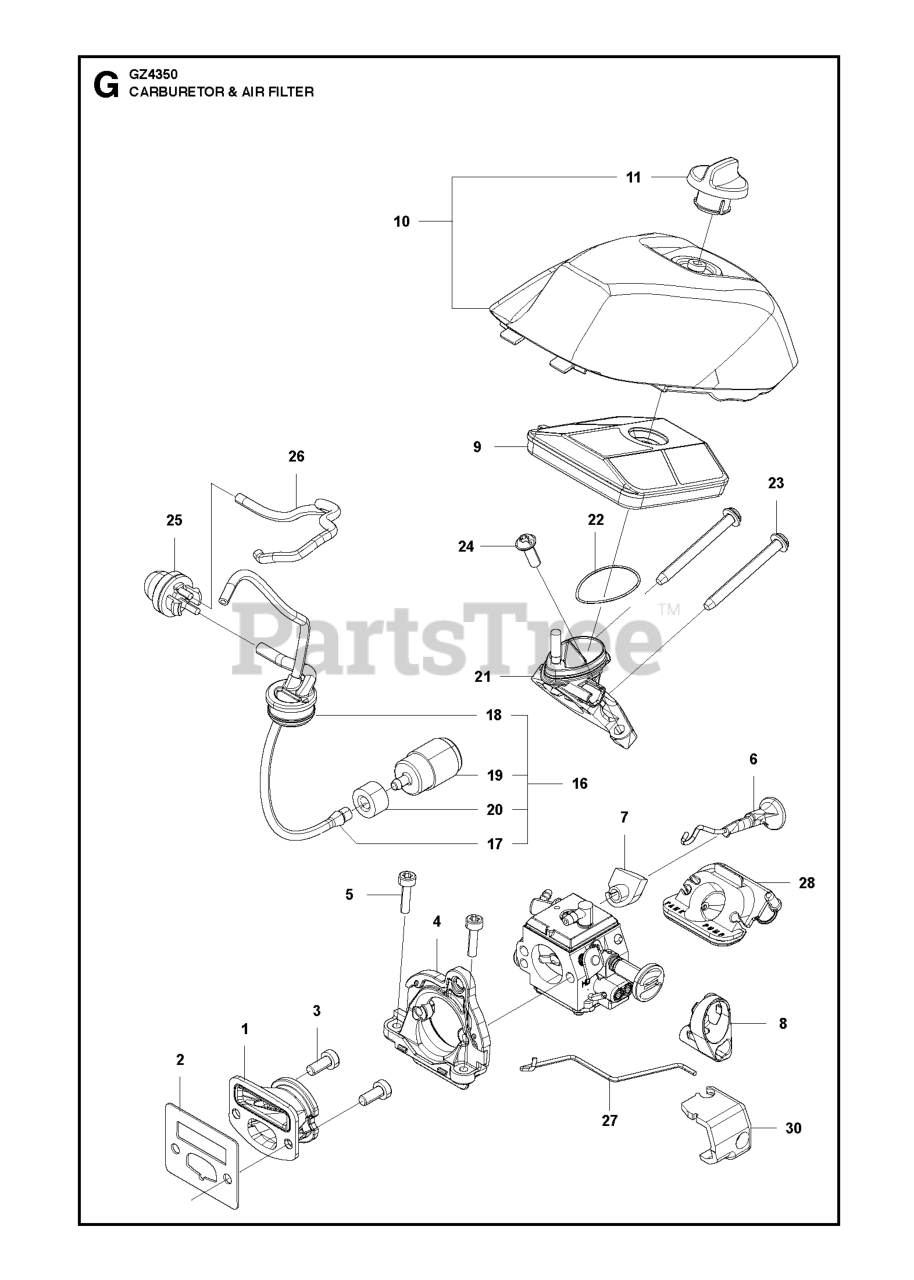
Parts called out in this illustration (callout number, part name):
1	FUEL HOSE
3	BOLT
4	FLANGE ASSY
5	BOLT
6	CHOKE ROD
7	GROMMET Z285082421
8	GROMMET ID
9	CLEANER COMP
10	AIR FILTER COVER ASSY
11	KNOB Z335683322
16	FUEL HOSE
17	FUEL HOSE L215
19	FILTER ASSY
21	MANIFOLD
24	SCREW M5 X 14
25	PRIMARY BTN
26	FUEL HOSE L170
27	THROTTLE ROD
30	GROMMET CARB
